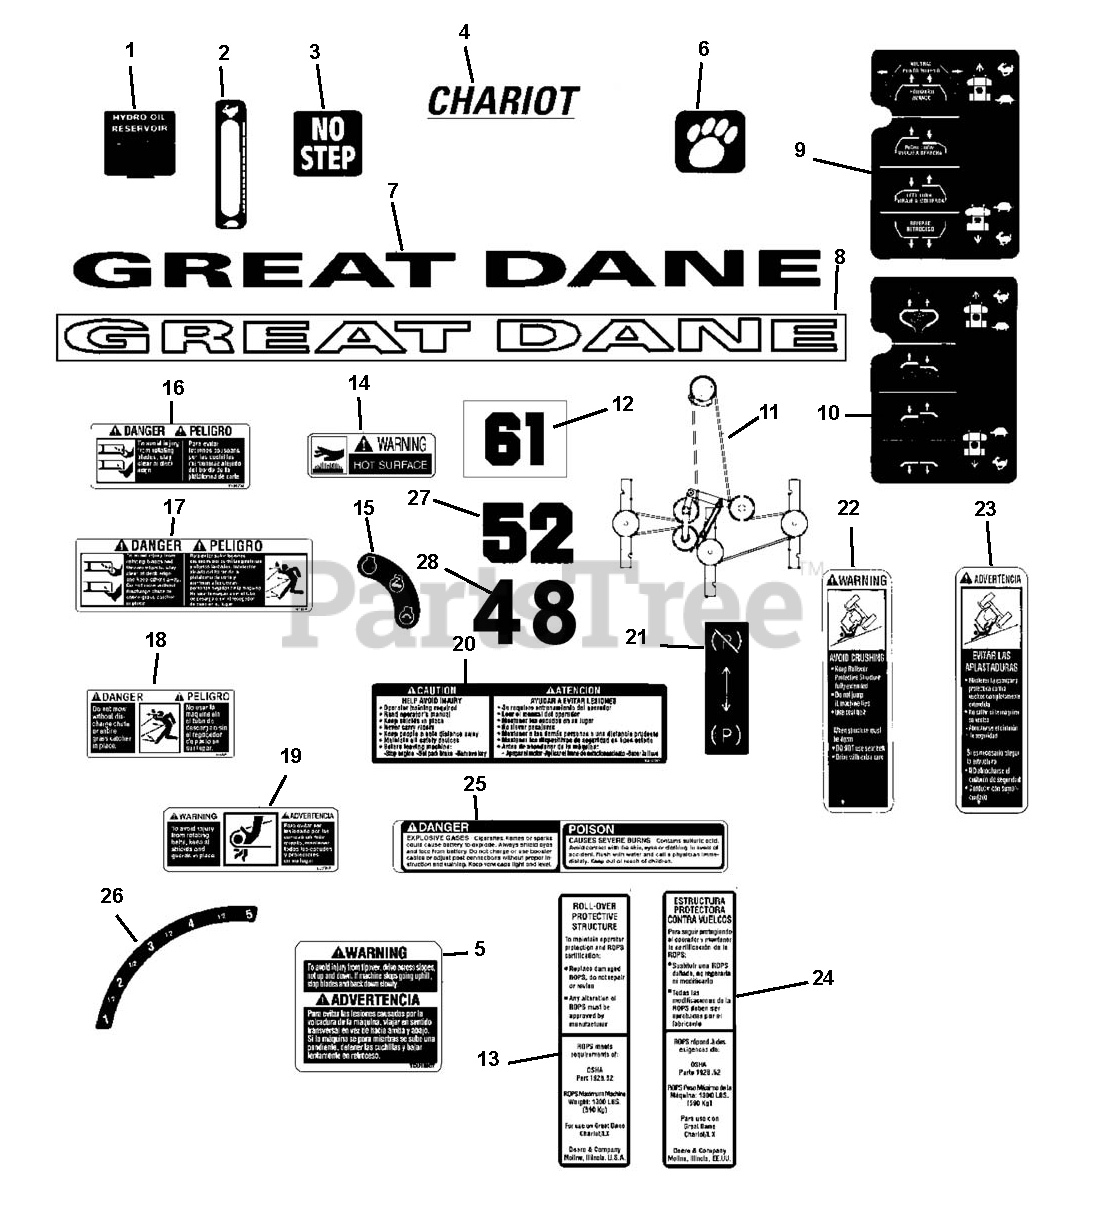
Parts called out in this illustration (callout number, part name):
1	SPACER, GAS TANK ATTACHMENT
2	DECAL, CONSOLE
3	LABEL, NO STEP
4	DECAL, CHARIOT
5	DECAL, WARNING - SLOPE
6	DECAL, PAW PRINT
7	DECAL, GREAT DANE
8	DECAL, GREAT DANE
9	DECAL, MOTION CONTROL (OVER LA
10	DECAL, MOTION CONTROL
11	DECAL, BELT PATH (48,52,61)
12	DECAL, 61
13	LABEL, ROPS CERTIFICATION (192
14	WARNING - HOT SURFACES
15	LABEL, IGNITION KEY
16	DECAL, DANGER - BLADE CONTACT
17	DECAL, DANGER - THROWN OBJECTS
18	LABEL, DISCHARGE
19	DECAL,DANGER
20	DECAL, GENERAL CAUTION
21	LABEL - PARK BRAKE DIRECTION
22	LABEL, WARNING ROPS (ENG)
23	LABEL, WARNING ROPS (SP)
24	LABEL, ROPS CERTIFICATION (192
25	LABEL, BATTERY
26	DECAL, HOC 1 - 4 1/2
27	DECAL, 52
28	DECAL, 48
